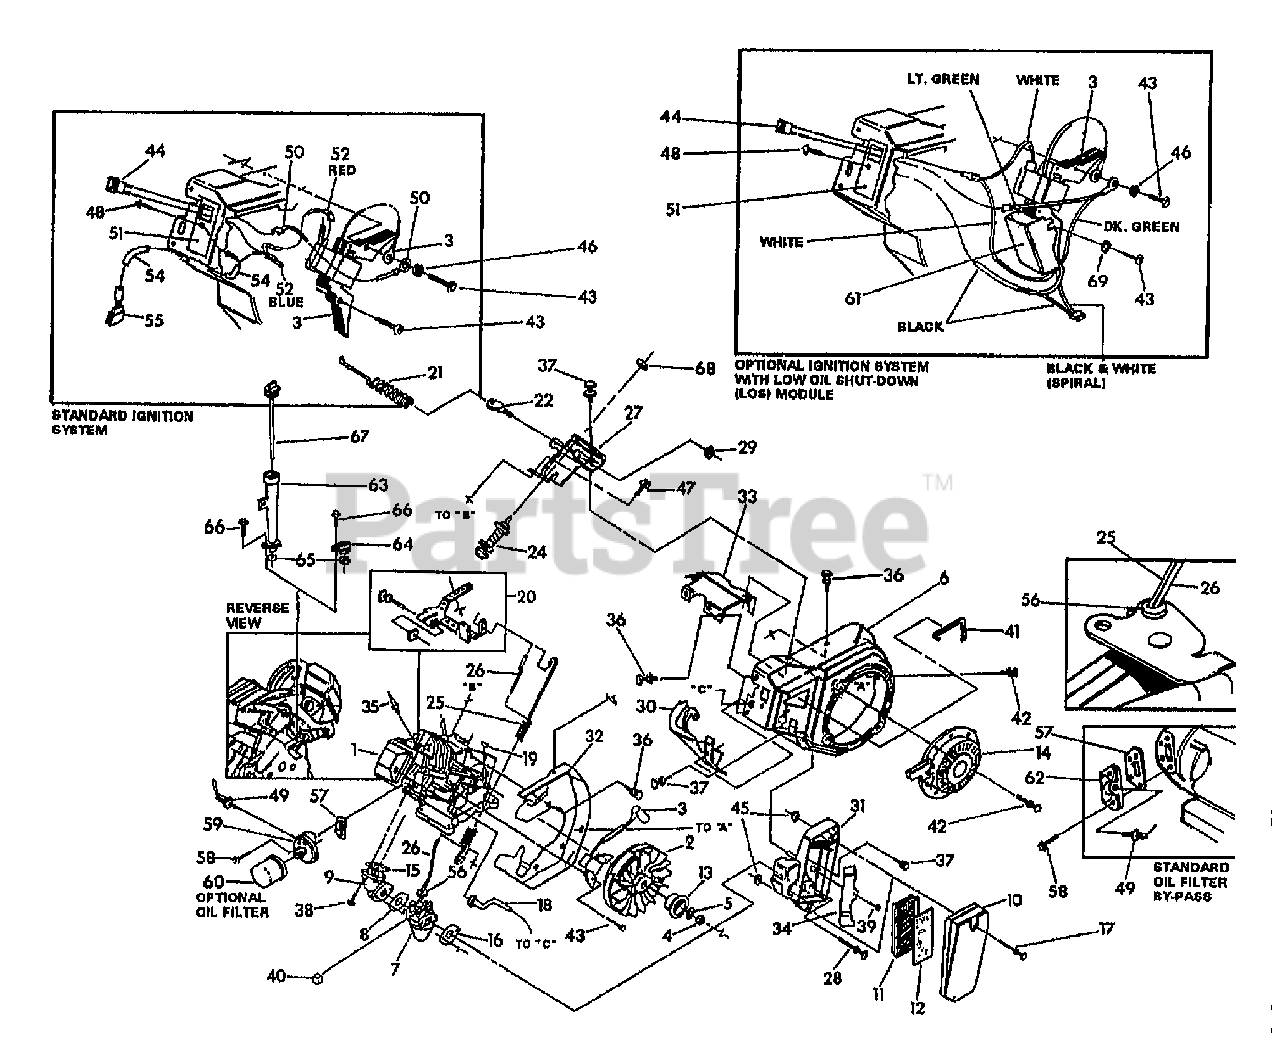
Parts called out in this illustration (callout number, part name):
1	ENG-GN220 LONG BLOCK STR SHFT
2	ASSM-FLYWHL 28 DEG TIMING(GEN)
3	ASSM-IGNITION COIL
4	NUT-HEX M16-1.5
5	WASHER-CONICAL
6	HSG-BLOWER (4000W GEN)
7	ASSM-CARBURETOR GN220HS
8	GASKET-CARB/MANIFOLD
9	MANIFOLD-INTAKE HS(4000W GEN)
10	COVER-AIR CLEANER
11	ELEMENT-AIR FILTER (4000W GEN)
12	PRE-CLEANER AIR FILTER
13	CUP-RECOIL
14	ASSM-RECOIL
15	GASKET-MANIFOLD/HEAD (4000W GE
16	GASKET-CARB/AIR CLEANER (4000W
17	SCR-AIR CLEANER COVER
18	HOSE-BREATHER (4000W GEN)
19	KEY-WOODRUFF 4X19
20	ASSM-GOVERNOR LEVER (4000W GEN
21	SPRING-GOVERNOR 60HZ
21	SPRING-GOVERNOR 50HZ (4000W GE
22	SCR-GOVERNOR ADJ
24	COIL-IDLE CNTRL (4000W GEN)
25	SPRING-ANTI LASH EXTENSION
26	ROD-GOVERNOR
27	FILTER-OIL (OPTIONAL)
29	NUT-LK M5-.8 MOUNTING
30	WRAPPER-LWR (4000W GEN)
31	BASE-AIR CLEANER
32	PLATE-BACK BLOWER HSG
33	WRAPPER-TOP ASSM (4000W GEN)
34	COVER-BREATHER CANAL
35	PLUG-SPARK CHAMPION RC12YC
36	SCR M6-1.0X10MM TAPTITE
37	SCR M6-1.0X12MM W/LK WSHR
38	SCR M6-1.0X30MM W/LK WSHR
39	SCR-M8X.375 PLASTITE
40	KNOB-CHOKE LEVER
41	SEAL-AIR CLEAN/BLWR HSG
42	SCR M6-1.0X10MM W/LK WSHR
43	SCR M6-1.0X30MM TAPTITE
44	SWITCH-SHUT OFF
45	NUT-HEX M6-1.0
46	WASHER
47	SCR-M8X15MM TAPTITE
48	ASSM-LED,LOW OIL IND. LIGHT
49	SWITCH-LOW OIL PRES 8-12PSI
50	ASSM-WIRE GROUND (4000W GEN)
51	DECAL-L.O.S. ENGINE
52	ASSM-WIRE IGNITION (4000W GEN)
54	#3 SLEEVING BLK 145 LG (4000W
55	HSG-3 PIN MALE
56	WASHER-CARBURETOR WEAR
57	GASKET-OIL FILTER PAD (4000W G
58	SCR-M6X1.0X20 TAPTITE
59	FILTER-ADAPTOR OIL (MC SERIES)
60	FILTER-OIL (OPTIONAL)
61	DECAL-BELT CAUTION C/V II
62	PIN-PISTON
63	TUBE-OIL FILL (OPTIONAL)
64	COVER-OIL FILL (4000W GEN)
65	GASKET-OIL FILL
66	SCR-M6 X 12 TAPTITE
67	DIPSTICK-OIL FILL(OPTIONAL)
68	NUT M8-1.25 HEX/JAM
69	WASHER-FLAT M6X12.5 OD
